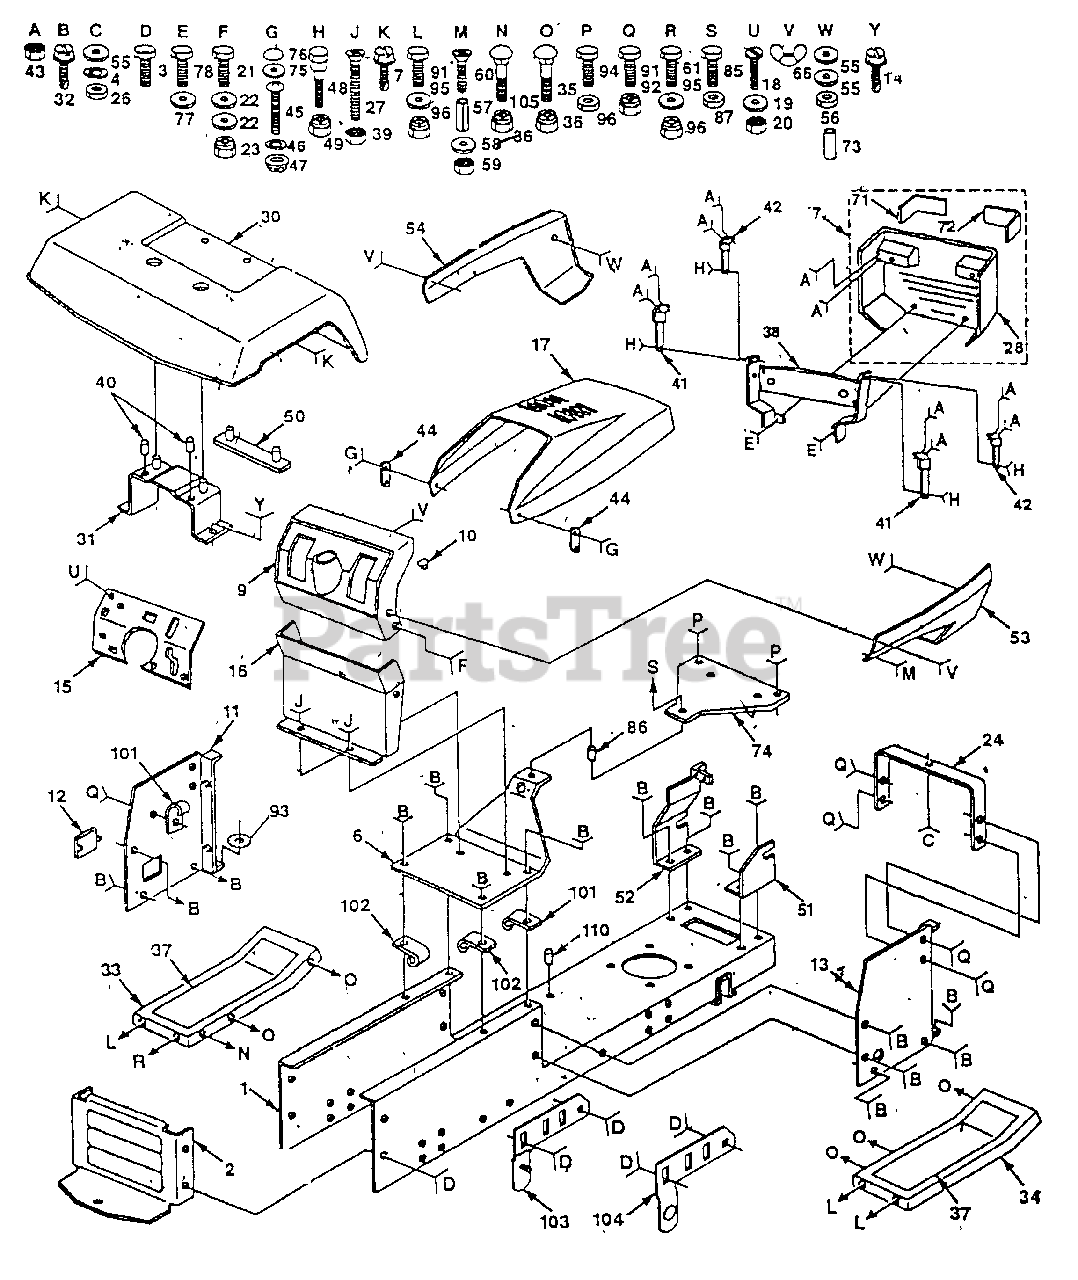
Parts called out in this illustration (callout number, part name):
1	Chassis Weldment 12 ga 38/42
2	Drawbar Stretch
3	Screw Thdrol 3/8 - 16 x 3/4 Ty-TT
4	Washer Lock Hvy Helical 1/4
6	Saddle Slkscr
7	Screw Thdrol 3/8 - 16 x Ty-TT
8	Washer Lock Hvy Helical 1/4
9	Dash Black Hole "a" 88
10	Plug Dash Blk 5009 Dis E Lift
11	Panel Pnt Dash Lh
12	Cover Access Black Square
13	Panel Pnt Dash Rh
14	Screw Thdrol 3/8 - 16 x 3/4 Ty-TT
15	Plate Silkscreened Dash
16	Dash Pnt Lower
17	Hood Pnt
18	Screw Mach Trhd 5/16 - 18 UNC x 3/4
19	Washer 11/32 x 11/16 x 16 Ga
20	Nut Keps 5/16 - 18 UNC
21	Bolt Fin Hex 3/8 - 16 UNC x 1 Gr.5
22	Washer 13/32 x 13/16 x 12 Ga
23	Nut Lock 3/8 - 16 Unc
24	Support Pnt Dash
25	Washer Lock Ext. Tooth 1/4
26	Nut Fin Hex 1/4 - 20 Unc
27	Screw mach Trhd 5/16 - 18 UNC x 3/4
28	Grille Asm
30	Fender Pnt
31	Bracket Pnt Fender
32	Screw Thdol 3/8 - 16 x 3/4 Ty-TT
33	Footrest Pnt Lh
34	Footrest Pnt Th
35	Bolt Rdhd Sht Sqnk 3/8 - 16 x 3/4
36	Nut Lock 3/8 - 16 Unc
37	Pad Footrest
38	Support Asm Grille
39	Nut Keps 5/16 - 18 UNC
40	Nut Push Nylon
41	Strap Asm Pnt Hinge Rear (blk)
42	Strap Asm Pnt Hinge Front
43	Nut Keps Hex 1/4 - 20 UNC
44	Latch Chute Blk
45	Screw Mach Cr Pan #10-24 x 1/2
46	Washer Lock #10
47	Nut Weld .327/.304 #10 - 4
48	Bolt, Shoulder 1/4 - 20 UNC
49	Nut Crownlock 1/4 - 20 UNC
50	Strap Asm. Fender
51	Bracket Asm Fr Pvt Hinge Rh
52	Bracket Asm Fr Pvt Hinge Lh
53	Panel Pnt Rh Side
54	Panel Pnt Lh Side
55	Washer 9/32 x 3/4 x 16 Ga
56	Nut Fin Hex 1/4 - 20 Unc
57	Spacer Split #10 x 3/4 Cad/Zin
58	Washer 7/32-x 1/2 x 18 Ga
59	Nut Keps #10 - 24 Unc
60	Screw Mach Cr Pan #10 - 24 x 1-1/4
61	Bolt Hex 3/8 - 16 x 3/4
66	Nut Plastic Locking Wng 1/4 - 20
71	Lens Headlight Lh Smoked
72	Lens Headlight Rh Smoked
73	Spacer 17/64 x 1/2 x 3/8
74	Plate Pnt Sprt Battery (blk)
75	Cap Snap Black
76	Cap Washer Snap Nat.
77	Washer 9/32 x 3/4 x 16 Ga.
78	Bolt Hex Fin 1/4 - 20 Unc 2-1/2
85	Bolt Fin Hex 5/16 - 18 Unc x 2 Gr. 2
86	Spacer Split 59/ x 1.25 Blk/zin
87	Nut Lock Hex w/Ins 5/16 - 18 Unc P
88	Bolt Fin Hex 5/16 - 18 x 3/4
89	Nut Keps Hex 5/16 - 18
91	Bolt Hex 3/8 - 16 x 3/4
92	Nut Lock 3/8
93	Washer Lock Ext. Tooth 3/8
94	Botl Fin Hex 3/8 - 16 Unc x 1-1/4
95	Washer 13/32 x 13/16 x 12 Ga
96	Nut Lock 3/8 - 16 Unc
101	Clip Insulator
102	Clip Line Fuel 13/32 Mtg Hole
103	Bracket Asm Pivot Lh
104	Bracket Asm Pivot Rh
105	Bolt Carriage
110	Bushing Snap Split
